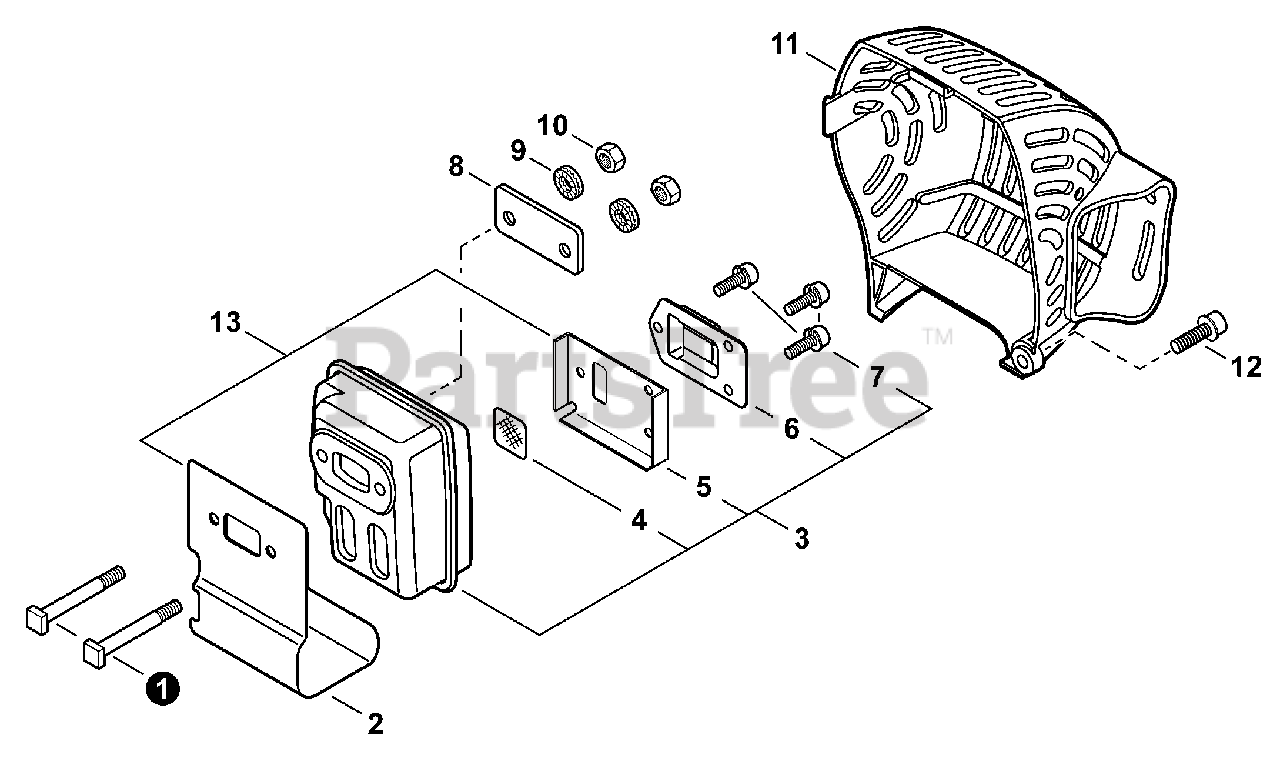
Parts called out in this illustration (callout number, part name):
1	BOLT 5×60
2	HEAT SHIELD, EXHAUST
3	MUFFLER ASSY
4	SCREEN, SPARK ARRESTER
5	GASKET, EXHAUST
6	GUIDE, EXHAUST
7	SCREW 4×10
8	PLATE, EYE
10	NUT M5
11	COVER, MUFFLER
12	BOLT 5×14
13	GASKET KIT
